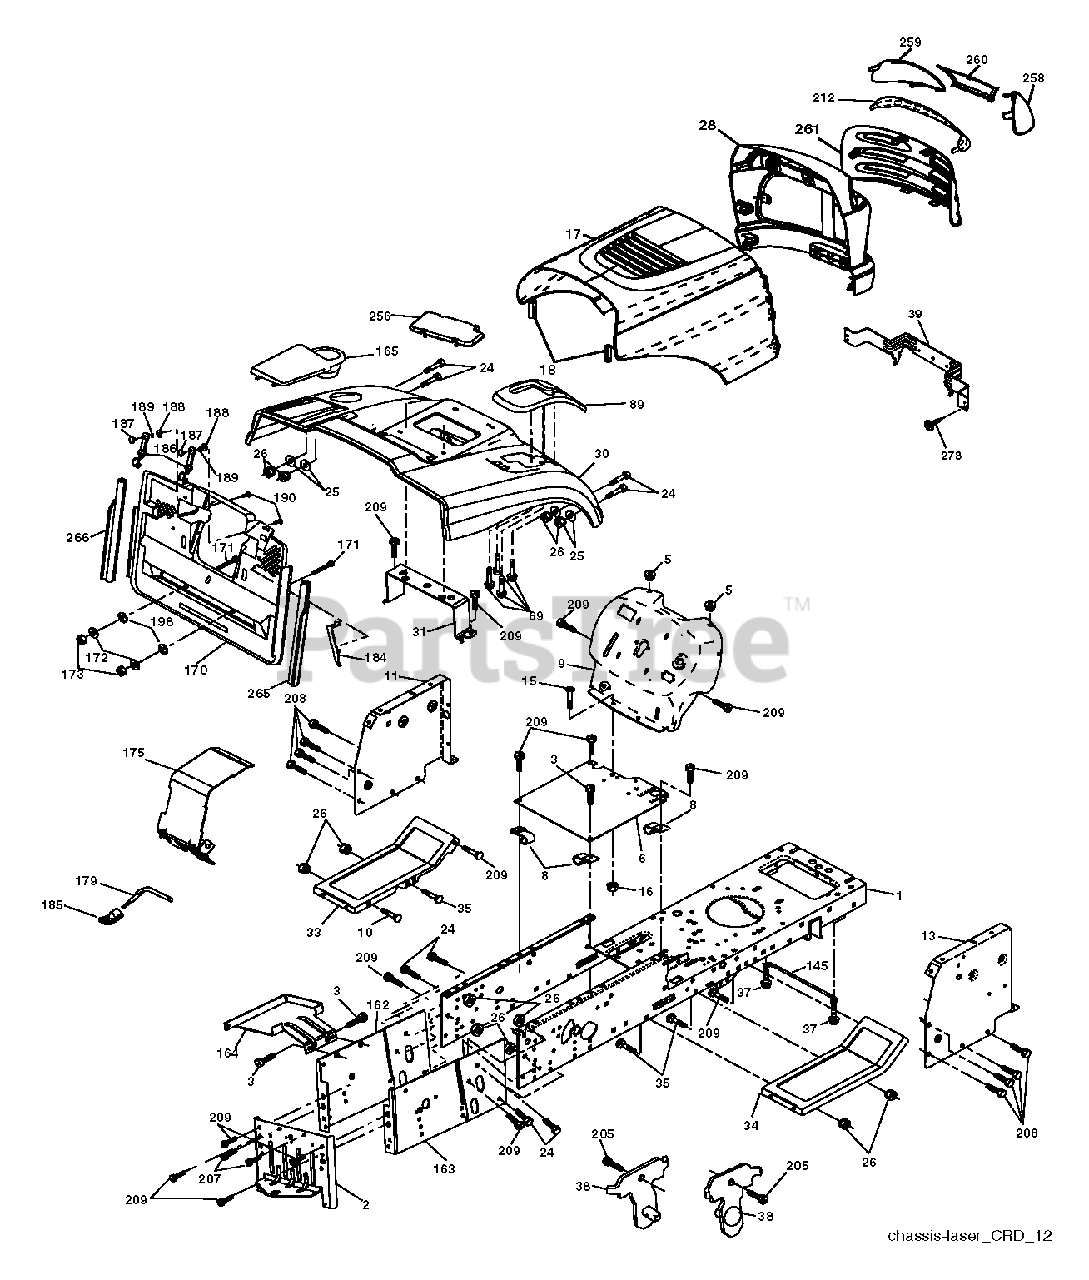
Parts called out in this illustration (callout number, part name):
1	CHASSIS
3	SCREW 3/8-16X3/4
5	BUMPER.RUBBER.HOOD
8	CLIP,INSULATOR
9	FENDER LT SH
10	BOLT D
11	PANEL.DASH.LH.LTX
13	PANEL DASH RH
16	NUT
18	BUMPER.HOOD.LARGE.1.75"
24	BOLT
25	WASHER
26	NUT
28	GRILLE.LASER II.DUAL.
30	FENDER.PNT.CRD.MS428 K
31	BRACKET SUPPORT FENDER
35	BOLT
37	SCREW LT
39	BRACKET PIVOT
69	SCREW.HI-LO.CONSOLE
145	ROD.PIVOT.HOOD
164	SUPPORT
165	FENDER.PNT.CRD.
171	BOLT
172	WASHER
184	BRACKET.ACTUATOR.BAGGER.SRD
185	KNOB.BRAKE.PARKING.ROD
186	LATCH ASSY
187	WELDNUT
190	SCREW
205	SCREW LT
207	SCREW, 5/16-18 X 1/2
208	SCREW 3/8-16X1/2
209	SCREW, 3/8-16X3/4
256	FENDER.PNT.CRD
258	LENS.LASER.2PC.LH.CLEAR.SVC
259	COVER.LENS.LASER.II
278	SCREW.#10 X 0.750.BOS THREAD
